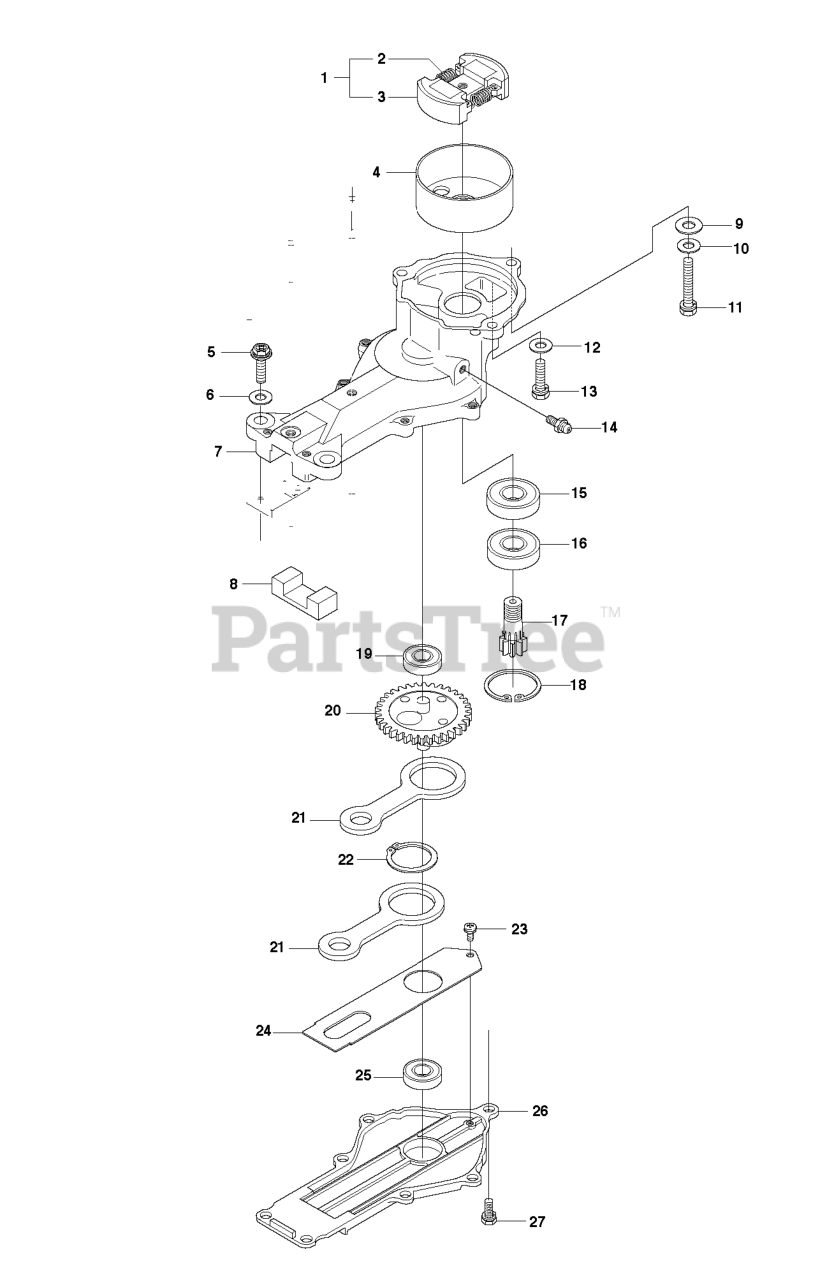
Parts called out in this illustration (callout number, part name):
4	CLUTCH DRUM
7	GEAR HOUSING
8	GREASE FILTER
9	WASHER - M6
11	BOLT FLANGE
14	GREASE FITTING
18	RETAINING RING
20	CRANK GEAR
22	RETAINING RING
